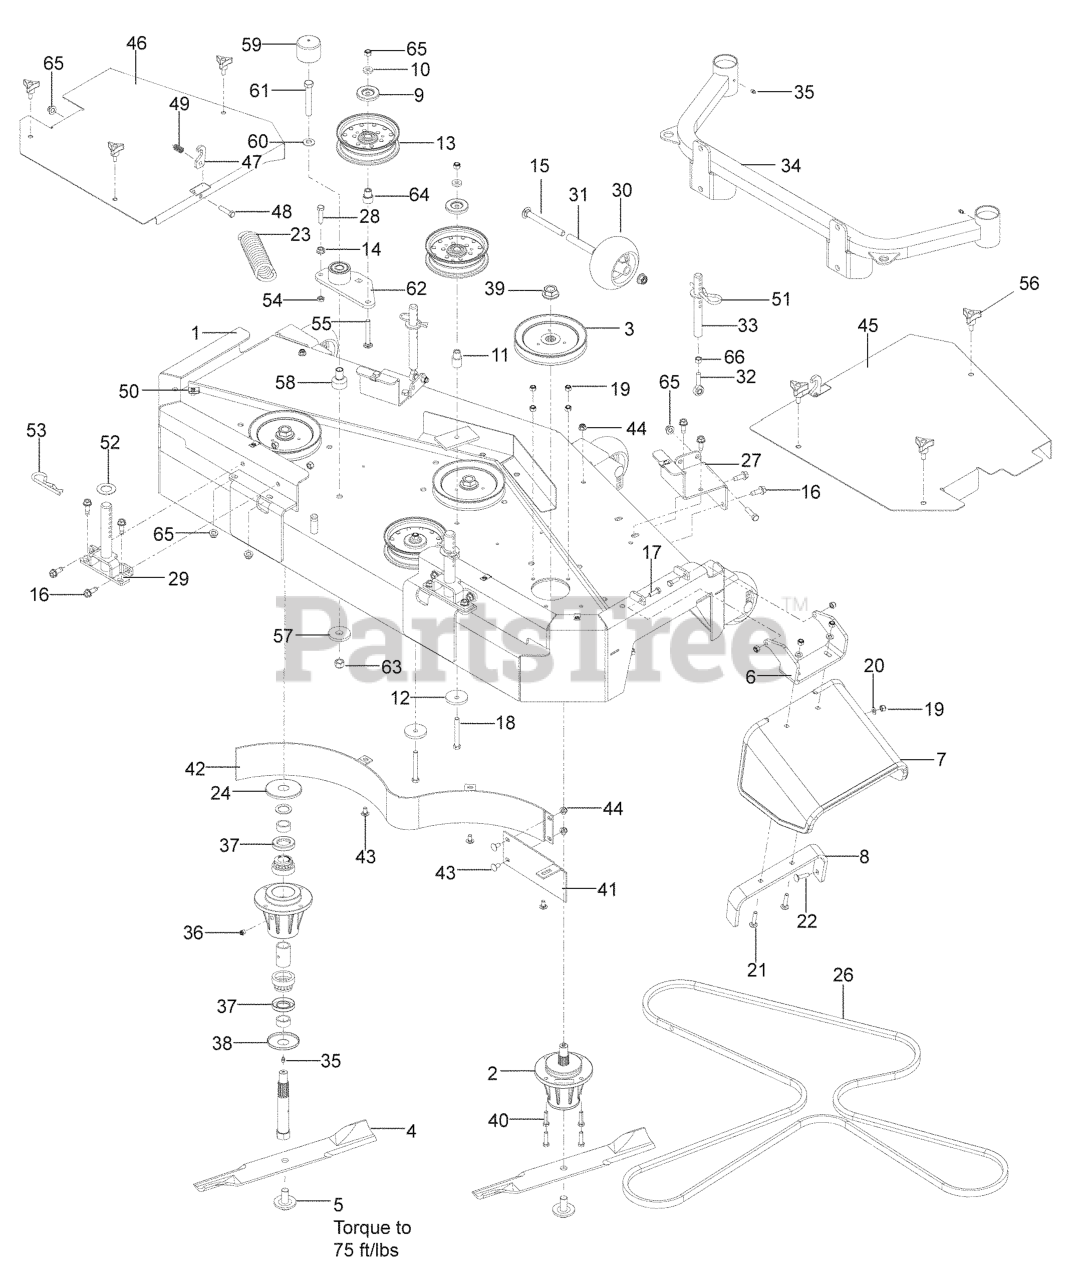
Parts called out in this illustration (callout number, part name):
1	CUTTER DECK w/DECALS
2	HOUSING ASM, 72
3	PULLEY - 7.50
4	BLADE OEM 21" (61" DECK)
5	BLADE BOLT/WASHER
6	HINGE CHUTE - BLACK
7	CHUTE, RUBBER DISCHARGE WB
8	BRKT, REINF-CHUTE WB
9	DUST SHIELD
10	WASHER, 3/8 THICK
11	IDLER BUSHING
12	SPINDLE WASHER
13	IDLER PULLEY
14	NUT 3/8C WHIZ
15	RHSNB 1/2-13 X 4.75 GR5 ZD
16	BOLT 3/8-16 X 1.0
17	HCS 5/16C X 1
18	HCS 3/8C X 3
19	NUT 5/16 NYLOC
20	FLAT WASHER 5/16 SAE
21	RHSNB 5/16-18 X 1-1/2 GR 5 ZD
22	BOLT, CARRIAGE 5/16X1-1/4
24	TOP DUST CAP
25	WASHER, 3/8 SPEC
26	BELT, B, 165
27	SUPPORT - FRONT, RH ORANGE
28	HCS 3/8-16 X 1-1/2
30	ROLLER, GAUGE .635 BORN
31	TUBE, ROLLER AXLE
32	ROD END - 3/8-24 RH
34	SUPPORT, CASTER 61 OR
35	ZERK
36	PLUG-VENTED
37	SHAFT SEAL
38	BOTTOM DUST CAP
39	NUT FLANGE 3/4-16
40	HCS 5/16C X 1 1/4
41	CENTER BAFFLE - 61
42	BAFFLE WLDMT 61 BLK
43	CARRIAGE BOLT 5/16C X 5/8"
44	5/16-18 NYLOC FLANGE NUT
45	COVER.61".RH.GREY
46	COVER.61".LH.GREY
48	HCS 3/8C X 1 1/2
49	SPRING - COMPRESSION
50	U-CLIP 5/16-18 NUT RETAINER
51	WASHER 3/4 FLAT SAE ZD
54	NUT 3/8-16 HEX JAM
55	RHSNB 3/8-16 X 2.75
56	KNOB W/STUD
57	WASHER, SUPPORT
58	PIVOT, BEARING
59	CAP, VINYL
60	CONTACT BELLSPR 1/2
61	HCS 1/2C X 3 1/4
62	ARM-IDLER W/BRG
63	NUT 1/2-13 HEX NYLOC ZD
64	BUSHING, IDLER
65	NUT 3/8-16 HEX FLG NYLOC ZD
